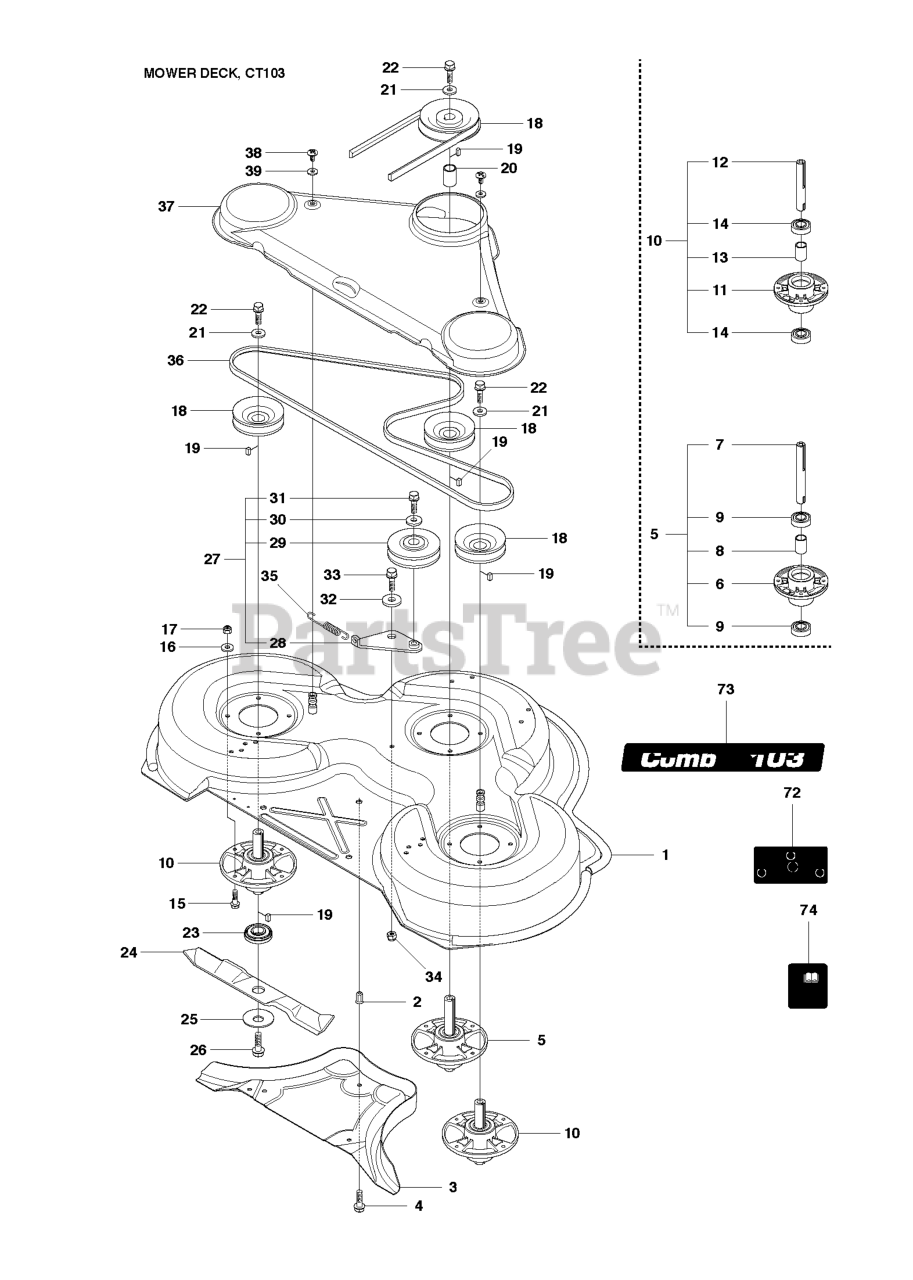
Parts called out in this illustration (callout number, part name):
6	BEARING HOUSING
9	BALL BEARING
11	BEARING HOUSING
14	BALL BEARING
16	WASHER BRB 8.4X17
17	LOCKNUT M8
27	BELT TENSIONER ASSY
28	BELT TENSIONING ARM
32	WASHER
34	LOCKNUT M8
42	LOCKNUT M8
48	LOCKNUT M8
50	PARALLEL ROD
54	BALL BEARING 6004-2RS1
55	PIVOT WHEELS
57	DECK ROLLER, FRONT
61	NUT
65	HUB CAP PIVOT WHEEL
67	LOCKNUT M8
71	LOCKNUT M8
